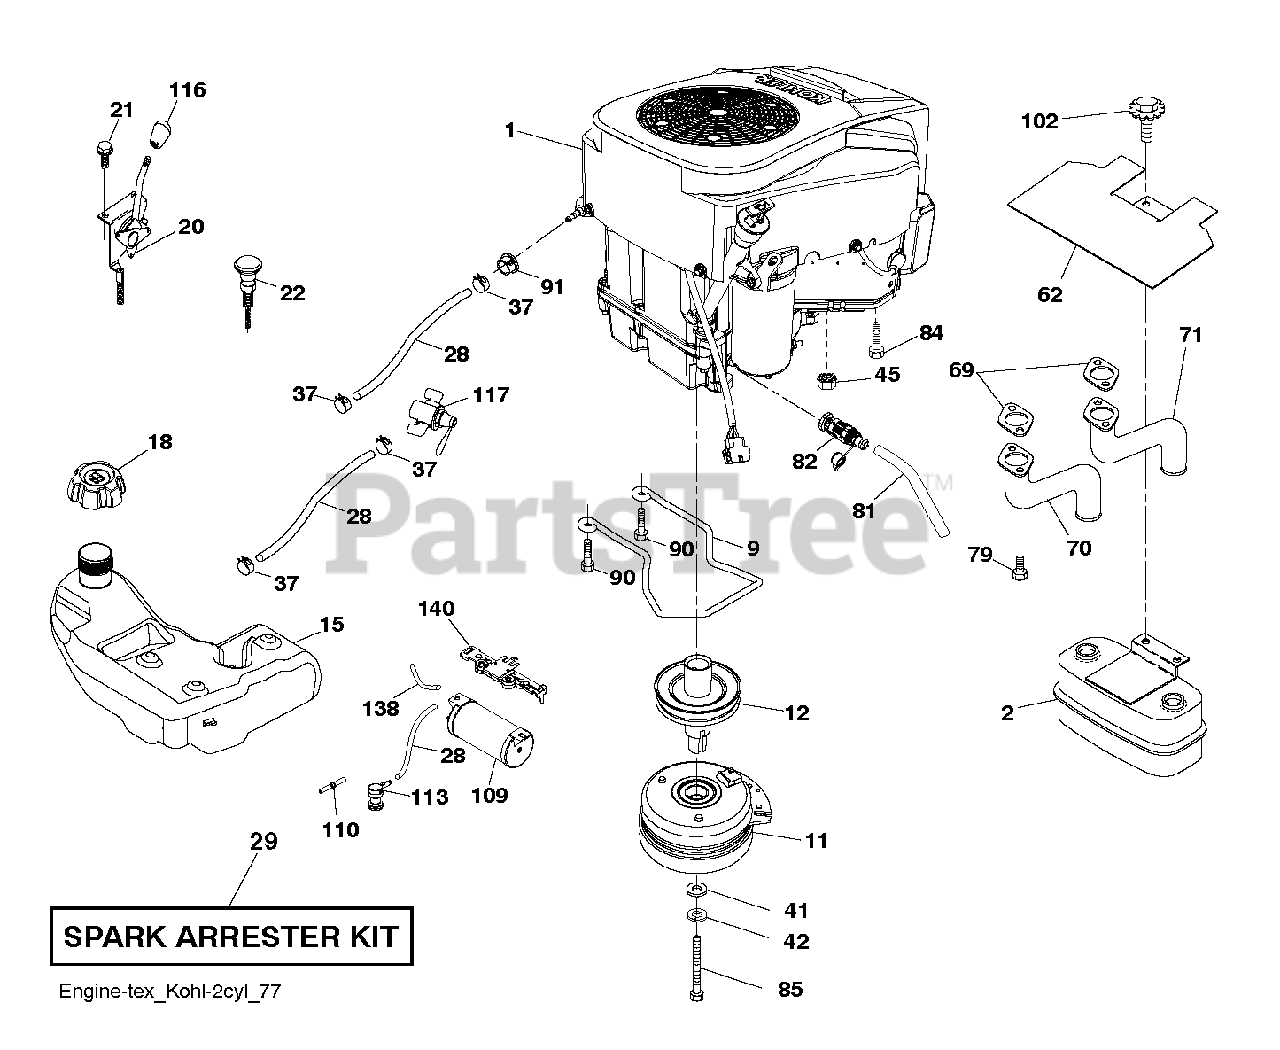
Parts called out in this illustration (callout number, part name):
2	Muffler Assembly, Twin MN
9	KEEPER.BELT.ENG.4.25"2.BLT.431
11	CLUTCH. 5.0 PD. 2.5 OFFSET
12	PULLEY.EXTENDED.SHAFT.GROUND
15	TANK.ASM.FUEL.4R.GAL.CARB.17
18	CAP ASSY FUEL 3" GRAY
20	THROTTLE.KOHL.PRO.#88PAD_46"
21	SCREW.#10 X 0.750.BOS
22	CONTROL.CHOKE.ERGO.PUSH-IN.BLA
28	Fuel Hose, 1/4" Low Perm
29	KIT.SPARK ARRESTOR 794945 B&S
37	HOSE CLAMP
42	WASHER 7/16 LOCK
45	NUT
62	SHIELD.HEAT.MUFFLER
69	GASKET.EXHAUST.KOHL.CV18-CV26
70	PIPE.EXHAUST.LH.CV18/20
71	PIPE.EXHAUST.RH.CV18/20
79	SCREW.SOCKET HD.5/16-1
81	TUBE, DRAIN OIL ASM.
82	VALUE.OIL.DRAIN
84	SCREW 3/8-16X1
85	BOLT.HEX.7/16-20X5.GR5.GREEN
90	SCREW 3/8-16X1
91	BUSHING.1.375OD
102	SCREW
109	CANISTER CARB, FLEX TECH, 6.3
110	VALVE.ASM.ANTI-SLOSH
113	VALVE.SLANT.CARTRDG.90 DEG.TEX
116	KNOB - SHIFT
117	VALVE FUEL RESERVE
138	RP PURGE LINE
140	BRACKET BRACKET, CARBON CAN, F
